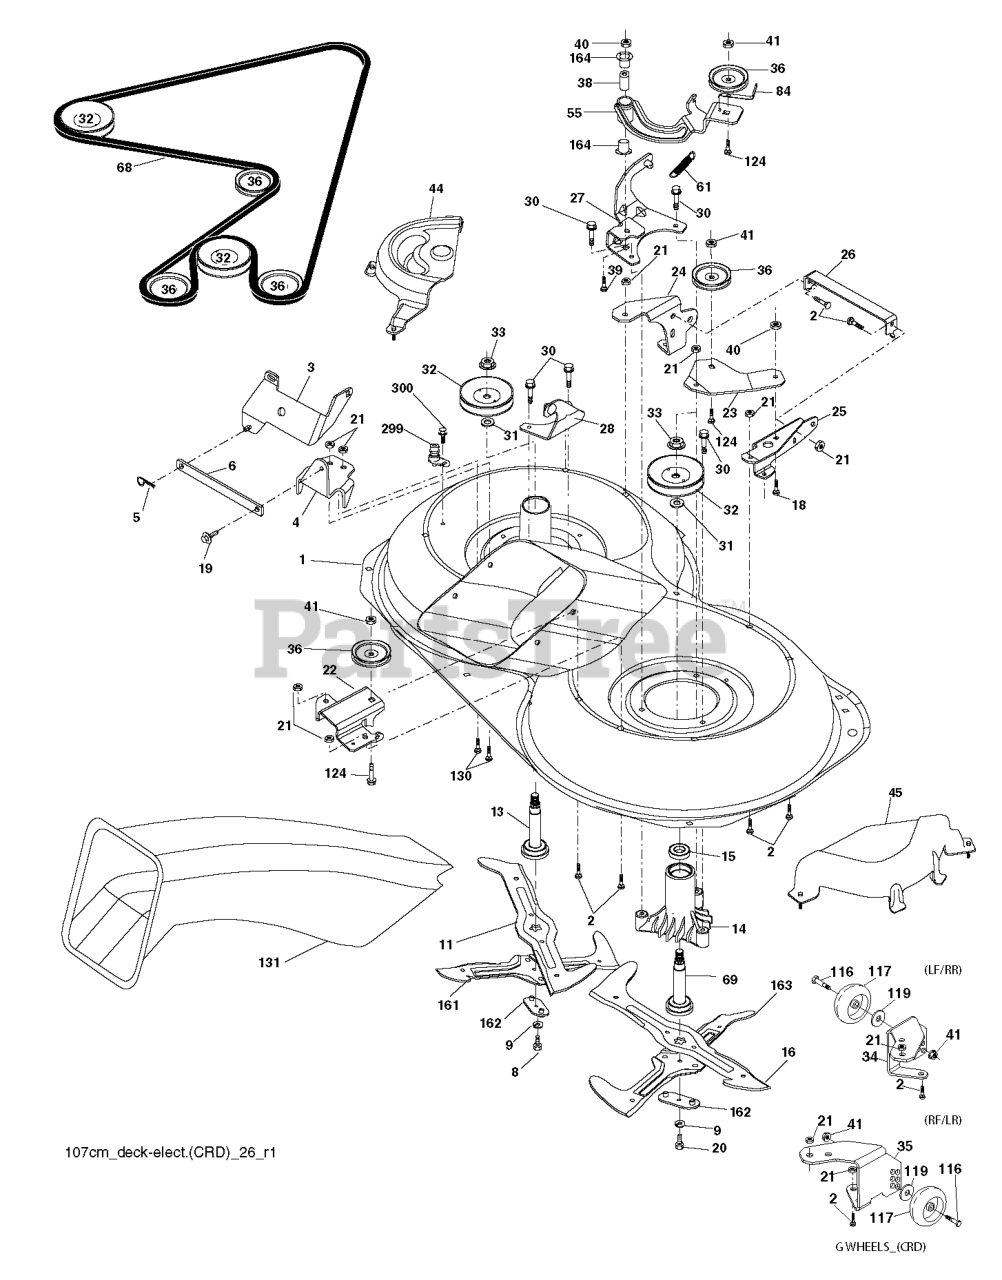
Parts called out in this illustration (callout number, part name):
1	Housing Asm. Mower 107 CRD
2	RP BOLT 5/16-18 X3/4 ZN/YEL GR
3	BRACKET.ASM.BAR.SWAY.CHASS
5	RETAINER-SPRNG RB
6	BAR.SWAY.92.CRD
8	BOLT.3/8-24X1.25 GR8
9	LOCKWASHER
11	BLADE.3N1.LH.CRD
13	SHAFT ASM VENT
14	HOUSING.MANDREL.VENTED (MACHD)
16	BLADE.3N1.RH.CRD
19	BOLT SHD 5/16-18
20	BOLT.3/8-24X1.25GR8. LHTHRD
21	LOCKNUT
22	BRACKET.IDLER.RR.107.CRD
24	BRACKET
25	BRACKET RF
26	SUPPORT
28	BRACKET
30	SCREW, WASHER HEAD
31	WASHER.SPACER.MANDREL
32	PULLEY.MANDREL.4.80 PD.2006
33	NUT.FLANGE.LOCK.TOP
34	BRACKET
35	BRACKET
36	PULLEY.IDLER.4.25
41	NUT LOCK FLG 3/8-16 UNC
55	ARM.IDLER.107.CRD
61	SPRING
68	HEX-BELT 107 MOWER
69	SHAFT.ASM.W/LWR.BRG.RH.THREAD
84	KEEPER, BELT IDLER
116	BOLT.SHOULDER.3/8-16X3-5/8.
117	RP WHEEL. GUAGE RALLY
119	WASHER
124	BOLT.3/8-16X1.50
130	BOLT.CARR.SQNK.5/16-18UNC.X3/4
131	CHUTE BAGGER
163	BLADE.CROSS.RH.CRD.107
164	BRNG T
299	PORT.WASHOUT
300	SCREW.TT.#10-32X.5.3/8.FLANGE
